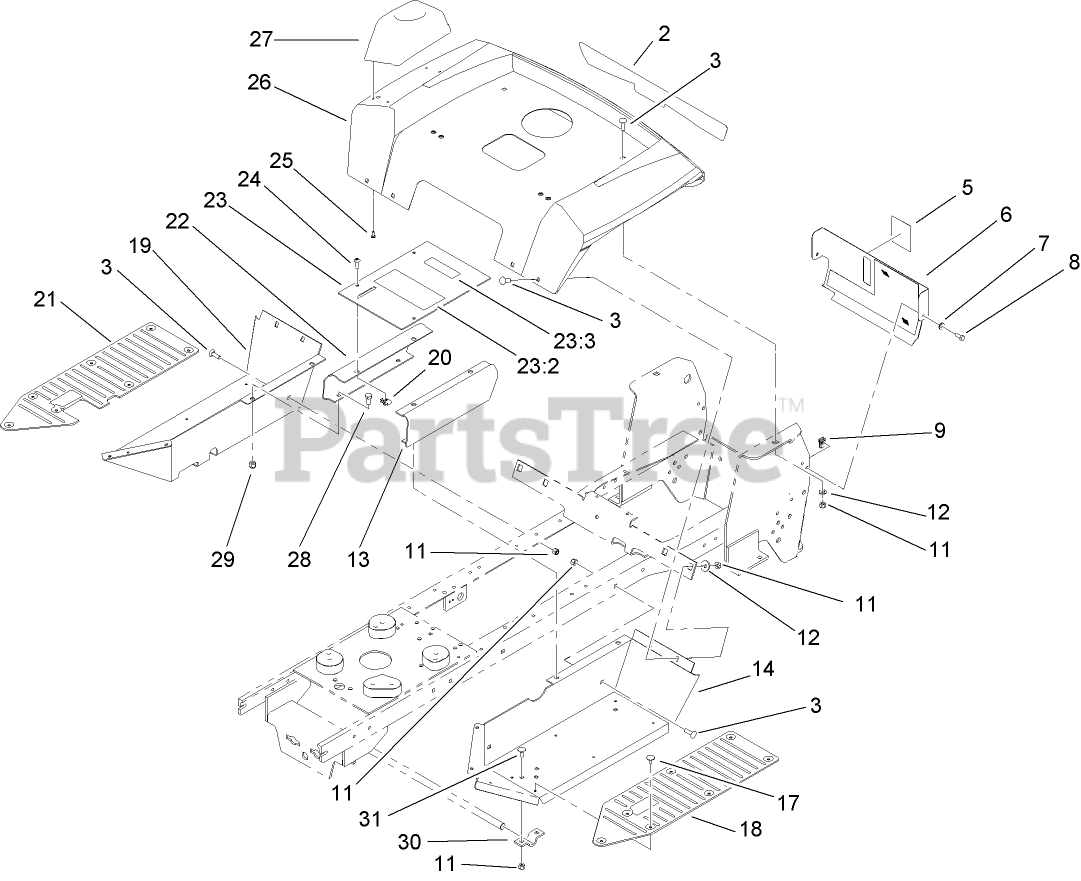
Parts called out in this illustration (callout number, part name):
2	DECAL-FENDER, REAR
3	SCREW-CARR
5	DECAL-LEVEL, FUEL
6	REAR PANEL ASM
7	WASHER-FLAT
8	SCREW-HH
9	NUT-SPEED
11	NUT-LOCK, NI
12	WASHER
13	CHANNEL-SADDLE, LH
14	FOOTREST-LH
17	FASTENER-PANEL
18	FOOTPAD-LH
19	FOOTREST-RH
21	FOOTPAD-RH
22	CHANNEL-SADDLE, RH
23	SADDLE PLATE DECAL ASM
23:2	DECAL-SLOPE/HYDRO
23:3	DECAL-MANUAL
24	SCREW-HH
25	SCREW-HWH
27	HOLDER-CUP
28	SCREW-HH
29	NUT-LOCK, NI
30	CLAMP
31	BOLT-CARR
